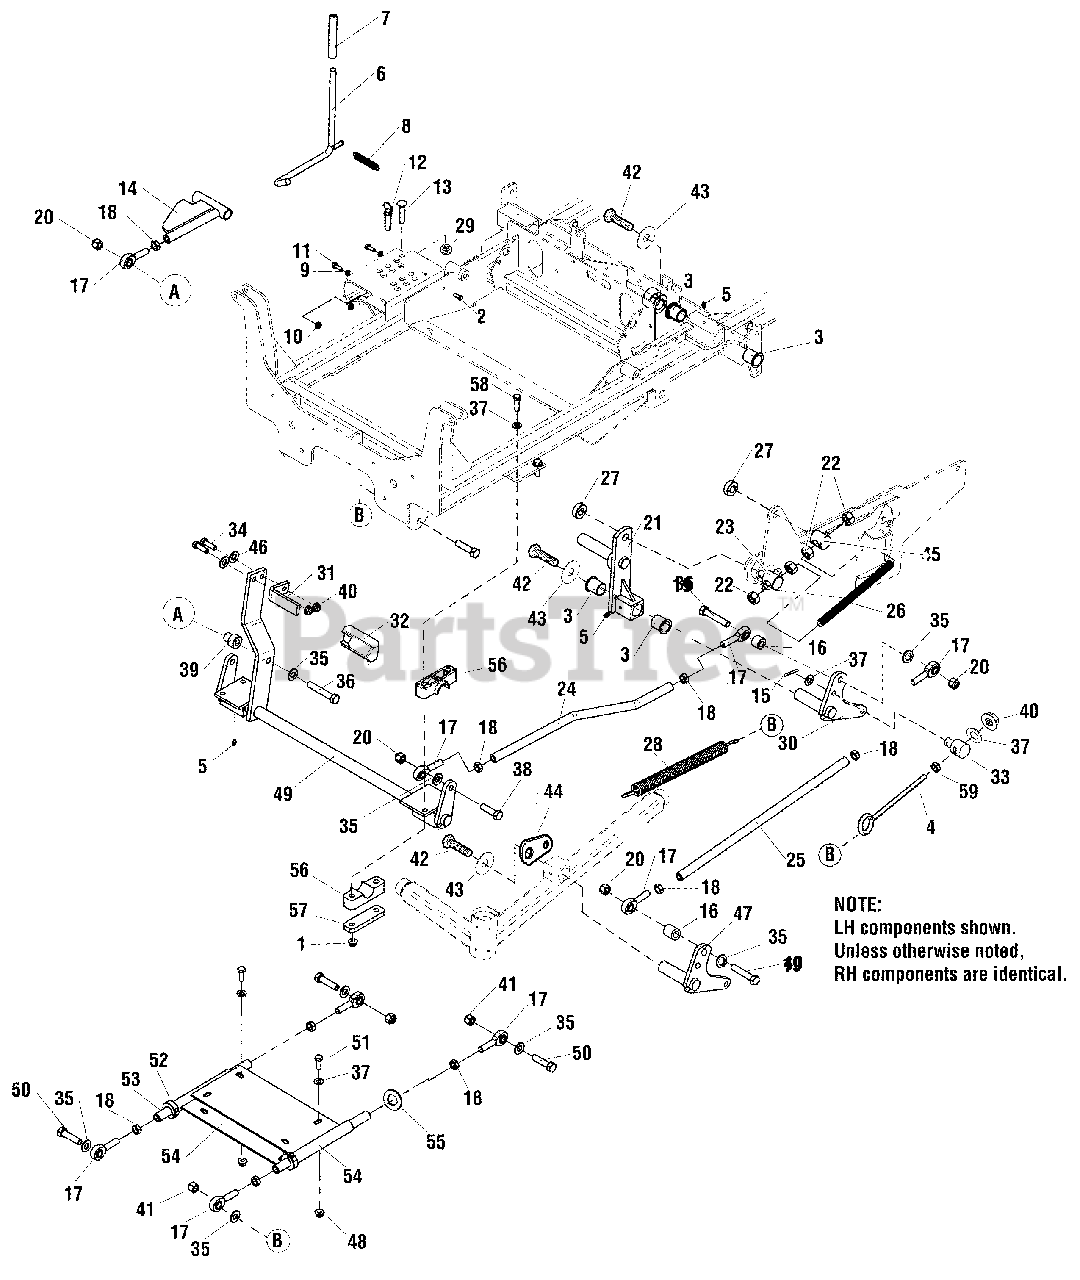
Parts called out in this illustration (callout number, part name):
1	NUT, 3/8-16 HEX NYLOCK FLANGE
2	PIN, CLEVIS, 1/4" x 7/8"
3	BUSHING, 1.00 X 1.13 X 1.38, PLASTIC
4	EYEBOLT, 3/2-16 X 8", 1" EYE
5	GREASE FITTING, 1/4-28 STRAIGHT
6	WELD, ROD DECK LIFT - BLK
8	SPRING, EXTENSION
9	WASHER, 1/4 SAE (5025154)
10	NUT, 1/4-20 HEX SERR. FLANGE
11	BOLT, 1/4-20 X 3/4" GD5 YZ
12	PIN, HITCH, 1/2 X 2.00 OAL, YP
13	BOLT, 3/8-16 X 2", CARRIAGE
14	WELD, DECK ADJUST LINK - ORANGE
15	PIN, COTTER, 1/8" X 3/4
16	SPACER, .52 X 1.00 X .75
17	BALL JOINT, 1/2-20, MALE
18	NUT, 1/2-20 HEX JAM
19	BOLT, 1/2-13 X 2-3/4" GD5
20	NUT, 1/2-13 HEX NYLON LOCK
21	WELD, REAR LIFT, LH - BLK
22	NUT, 5/8-11 HEX
23	PIVOT, SPRING ROD
24	ROD, DECK LIFT BENT
25	ROD, DECK LIFT, OUTER
26	ROD, 5/8-11 X 9.00
27	COLLAR, 5/8" SPLIT
28	SPRING, DECK LIFT ASSIST
29	NUT, 3/8-16 HEX SIDE LOCK
30	WELD, DECK LIFT LEVER, LH - BLK
31	PEDAL, FOOT - BLK
32	RUBBER, FOOT PEDAL
33	ADJUSTER, DECK HANGER
34	BOLT, 3/8-16 X 1-1/4" GD5
35	WASHER, 1/2" SAE
36	BOLT, 1/2-13 X 3-1/2" GD5
37	WASHER 3/8" SAE
38	BOLT, 1/2-13 X 1-3/4" GD5 YZ
39	ADAPTER, CASTER AXLE
40	NUT, 3/8"-16 HEX NYLON LOCK
41	NUT, 1/2-20 HEX NYLON LOCK
42	BOLT, 3/8-16 x 3/4, GD5, YZ WITH PATCH
43	WASHER, .390 X 1.50 X .109, YZ
44	MOUNT, SPRING DECK LIFT - ORANGE
45	PIVOT, SPRING ROD
46	WASHER, 3/8" GR9 FLAT
47	WELD, PIVOT DECK LIFT - LH - ORANGE
48	NUT, 3/8-16 HEX SERRATED FLANGE
49	WELD, DECK LIFT SHAFT - ORG
50	BOLT, 1/2-20 X 1-3/4" GD5 YZ
51	BOLT, 3/8-16 X 1" GD5 YZ
52	COLLAR, 3/4" SPLIT
53	SHAFT, DECK STABILIZER
54	WELD, DECK STABILIZER - BLK
55	WASHER, 1/2" SAE
56	PIVOT BLOCK, PLASTIC
57	PLATE, PIVOT BLOCK SUPPORT - BLK
58	BOLT, 3/8-16 X 2-3/4 GD5 YZ
59	NUT, 3/8-16 HEX
